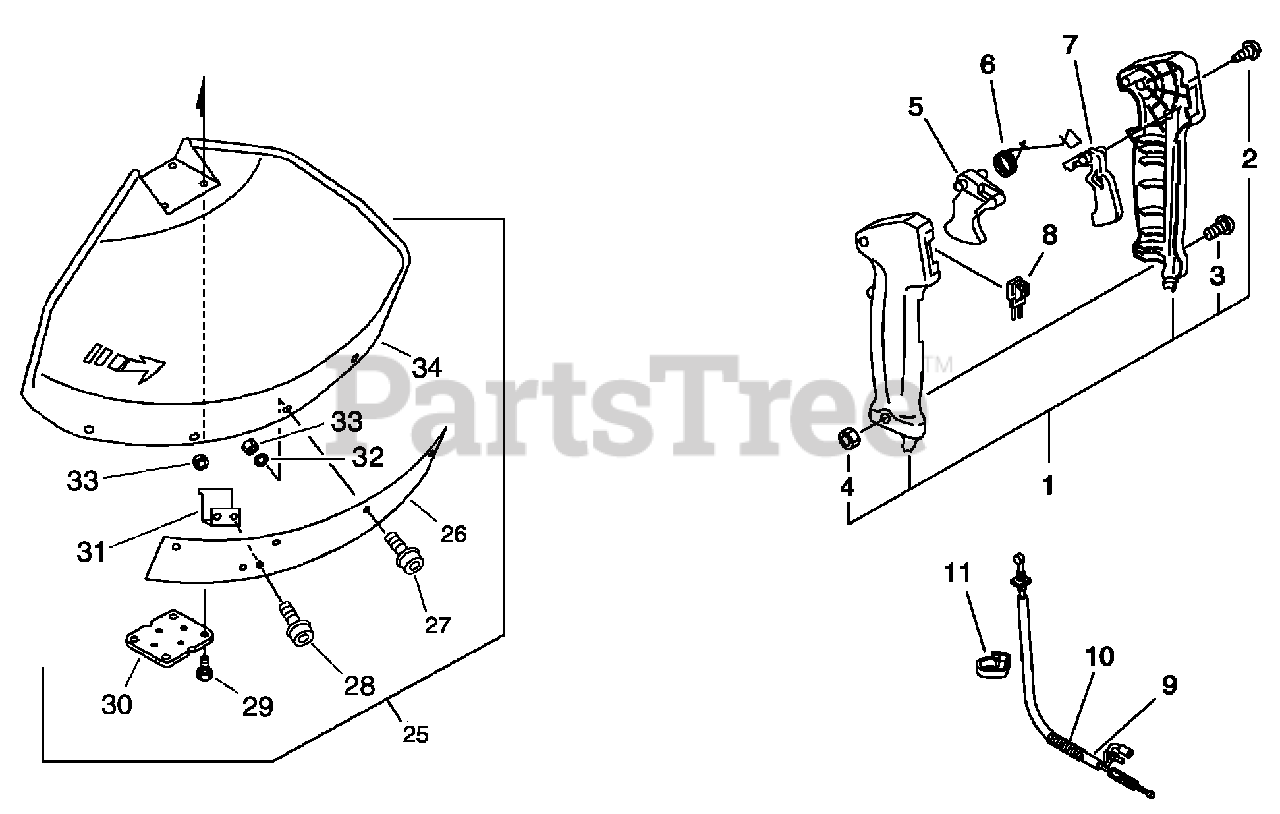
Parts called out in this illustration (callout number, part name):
1	CONTROL HANDLE KIT
2	SCREW 3×25
3	SCREW 5×30
4	NUT M5
5	TRIGGER, THROTTLE
6	SPRING, TORSION
7	LOCKOUT, THROTTLE
8	SWITCH, ON-OFF
9	CABLE, THROTTLE
10	TUBE, FLEXIBLE 7×790
25	DEBRIS SHIELD ASSY
26	EXTENSION, SHIELD
27	SCREW 5×18
28	BOLT 5×14
29	BOLT 5×25
30	PLATE, SHIELD
31	CUTTER, LINE
32	WASHER 5.5×12×0.8
33	NUT M5
34	SHIELD, DEBRIS
